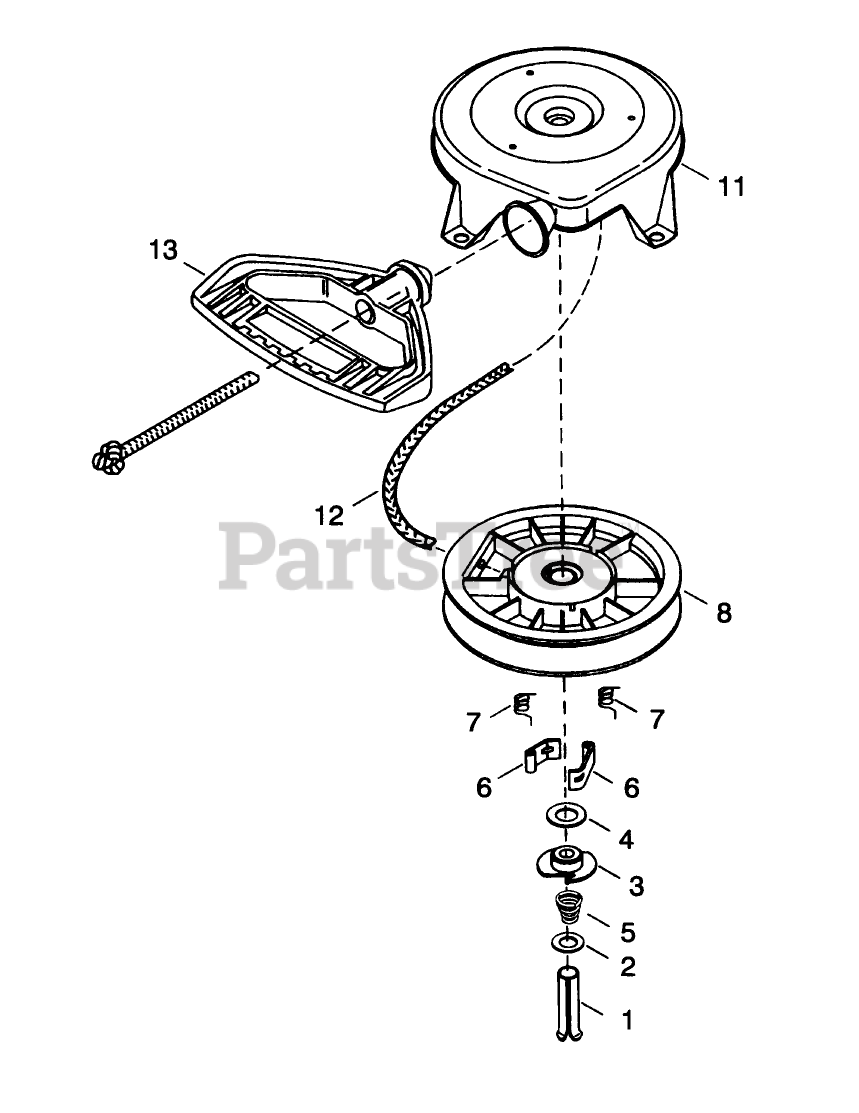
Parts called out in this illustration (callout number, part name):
1	Pin, Spring (Incl. Ref. #7)
2	Washer
3	Retainer
4	Washer
5	Spring-Brake
6	Dog-Starter
7	Spring-Dog
8	Pulley and Rewind Spring ASM
11	Housing Assy.-Starter
12	Rope-Starter
13	Handle-Starter, Mitten Grip
